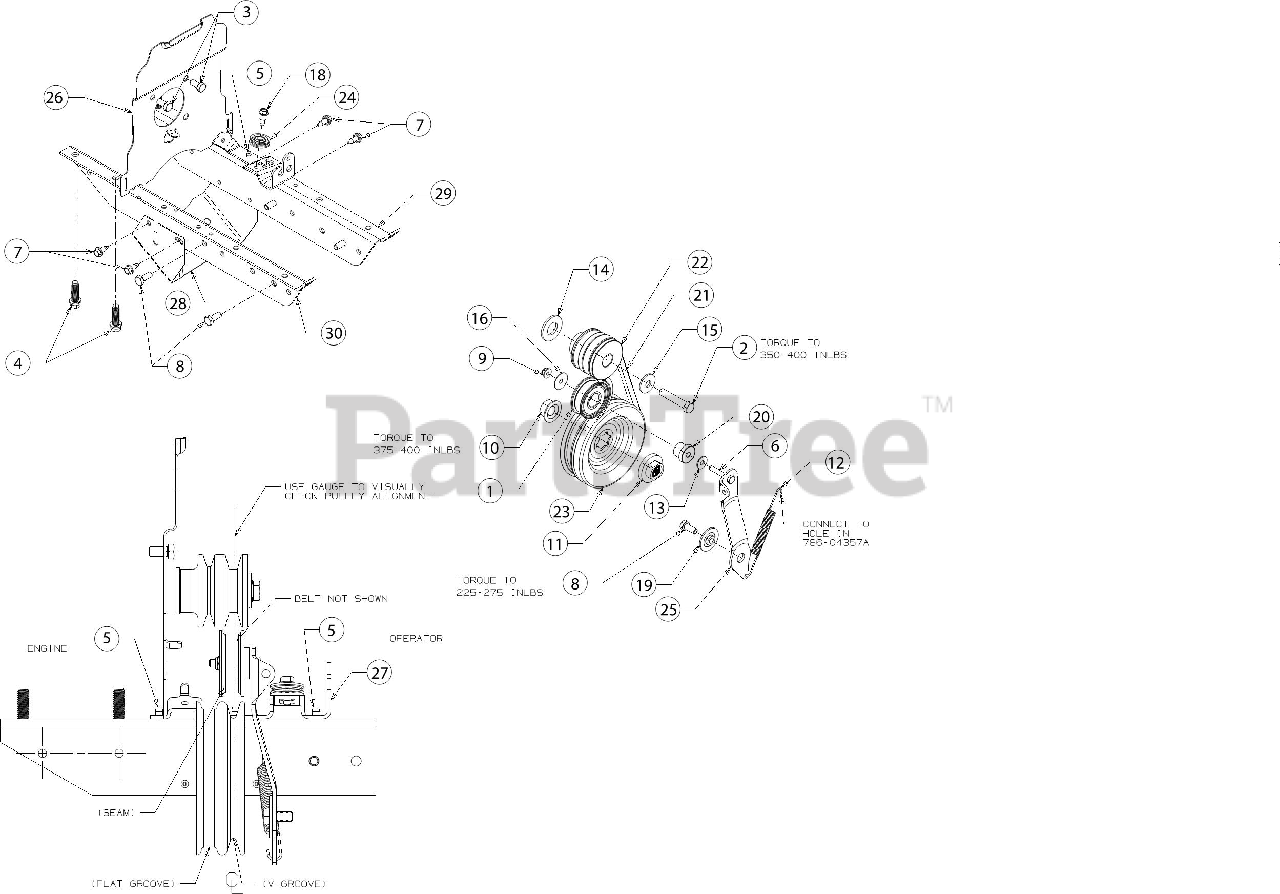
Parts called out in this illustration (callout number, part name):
1	IDLER PULLEY ASSEMBLY
1	BEARING SLEEVE
1	BALL BEARING
2	HEX SCREW 3/8-24 X2.00
3	HEX SCREW 5/16-24 x .62
4	SCREW 3/8-16 x 1.250
5	SCREW 1/4-20 X.500
6	SCREW 1/4-20 x 1.50 GR.5
7	SCREW 1/4-14 x .625
8	SCREW 5/16-18 x .750
9	FLANGE LOCK NUT
10	FLANGE NUT W/HUB
11	PULLEY HUB
12	RETURN SPRING
13	FLAT WASHER .28 ID x .74 OD x .063
14	FLAT WASHER
15	BELL WASHER
16	FLAT WASHER
18	SHOULDER SCREW
19	PIVOT IDLER SPACER
20	SHOULDER SPACER
21	V-BELT FWD DRIVE 4L x 25.375
22	ENGINE PULLEY
23	TRANSMISSION PULLEY
24	CABLE GUIDE ROLLER
25	FORWARD IDLER BRACKET
26	REVERSE IDLER BRACKET
27	CABLE BRACKET ROLLER
28	PULLEY SHIELD
29	FRAME-MOUNT (RH)
30	FRAME-MOUNT (LH)
